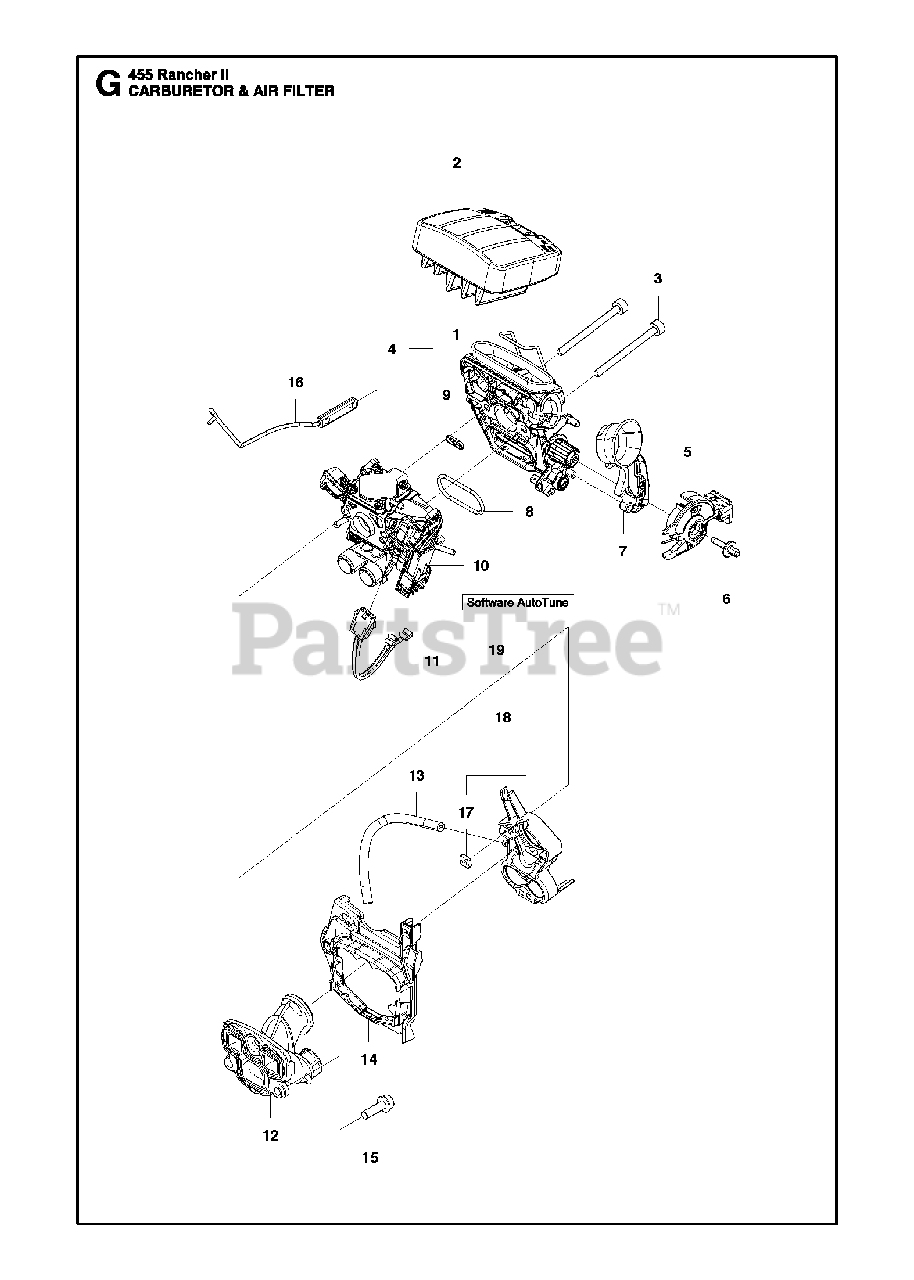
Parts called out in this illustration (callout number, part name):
1	SHACKLE
2	AIR FILTER ASSY
3	SCREW
5	CHOKE CONTROL ASSY
10	CARBURETOR
11	WIRING ASSY
12	INLET PIPE ASSY
13	HOSE
15	SCREW
16	THROTTLE ROD
17	NUT
19	Husqvarna TBD
